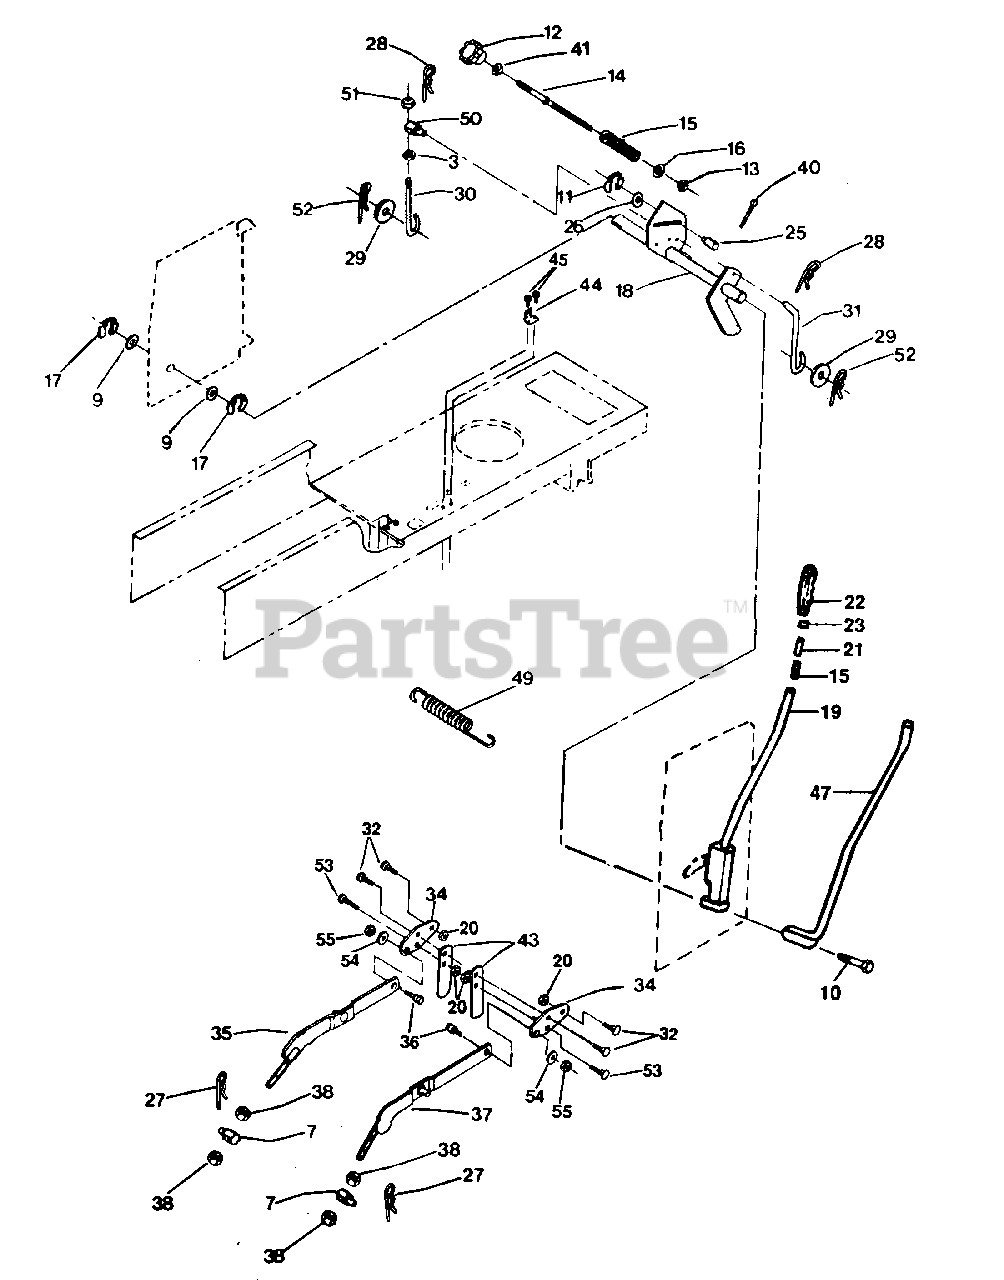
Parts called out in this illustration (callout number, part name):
3	Jam Locknut (AYP part number)
7	Lower Lift Trunnion (AYP part number)
9	Washer (AYP part number)
10	Hex Bolt (AYP part number)
11	Klip Ring (AYP part number)
12	Lift Adjust Handle (AYP part number)
13	Special Nut (AYP part number)
14	Lift Adjust Rod (AYP part number)
15	Spring (AYP part number)
16	Washer (AYP part number)
17	E-Ring (AYP part number)
18	Lift Shaft (AYP part number)
19	Lift Lever (AYP part number)
20	Crownlock Nut
21	Lever Plunger (AYP part number)
22	Handle Grip (AYP part number)
23	Plunger Button (AYP part number)
25	Stop Depth Trunnion
26	Washer (AYP part number)
27	Spring Retainer (AYP part number)
28	Spring Retainer (AYP part number)
29	Washer (AYP part number)
30	Adjust Link Lift (AYP part number)
31	Lift Link (AYP part number)
32	Carriage Bolt 3/8-16 x 3/4 (AYP part number)
34	Bracket Suspension (AYP part number)
35	L.H. Arm Suspension (AYP part number)
36	Shoulder Bolt (AYP part number)
37	R.H. Arm Suspension (AYP part number)
38	Fin. Hex Nut (AYP part number)
40	Cotter Pin (AYP part number)
41	Jam Hex Nut (AYP part number)
43	Mower Upstop (AYP part number)
44	Switch Bracket (AYP part number)
45	Tap Hex Screw (AYP part number)
47	Lever Rod Assembly (AYP part number)
49	Extension Spring (AYP part number)
50	Lift Trunnion (AYP part number)
51	Jam Crownlock Nut (AYP part number)
52	Retainer Spring (AYP part number)
53	Carriage Bolt 3/8-16 x 1 (AYP part number)
54	Spring Washer (AYP part number)
55	Flange Locknut (AYP part number)
